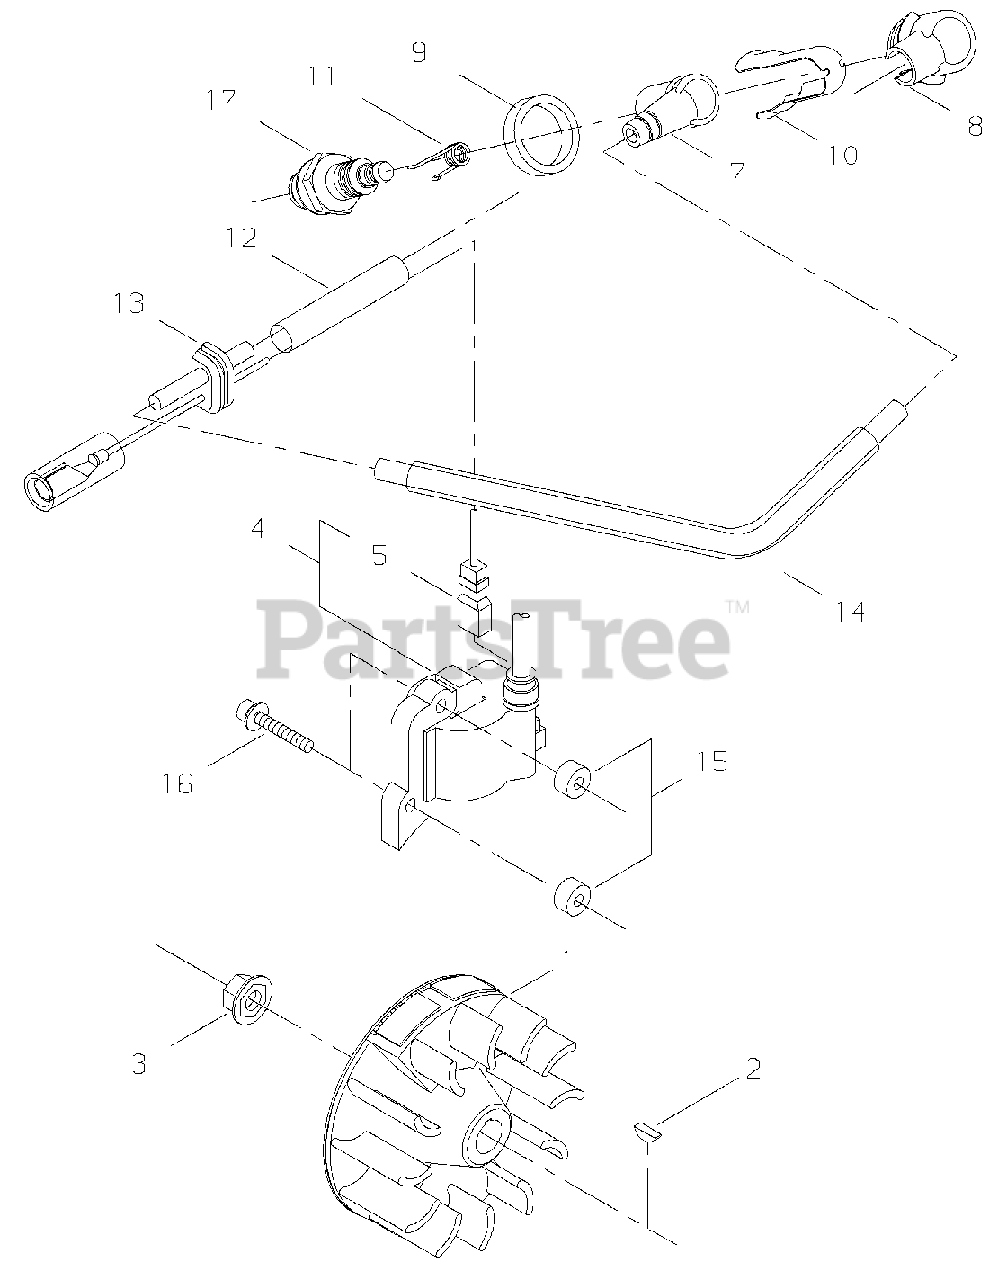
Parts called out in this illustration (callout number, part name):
2	KEY - 3X10
3	NUT - 8
4	IGNITION COIL ASSY
5	LEAD - IGNITION
7	CAP, SPARK PLUG
8	CAP, SPARK PLUG
9	SEAL, DUST
10	SHIELD
11	TERMINAL, SPARK PLUG CAP
12	TUBE
13	GROMMET
14	TUBE
15	INSULATOR
16	SCREW - 4X26
17	SPARK PLUG -- BMR-6A
